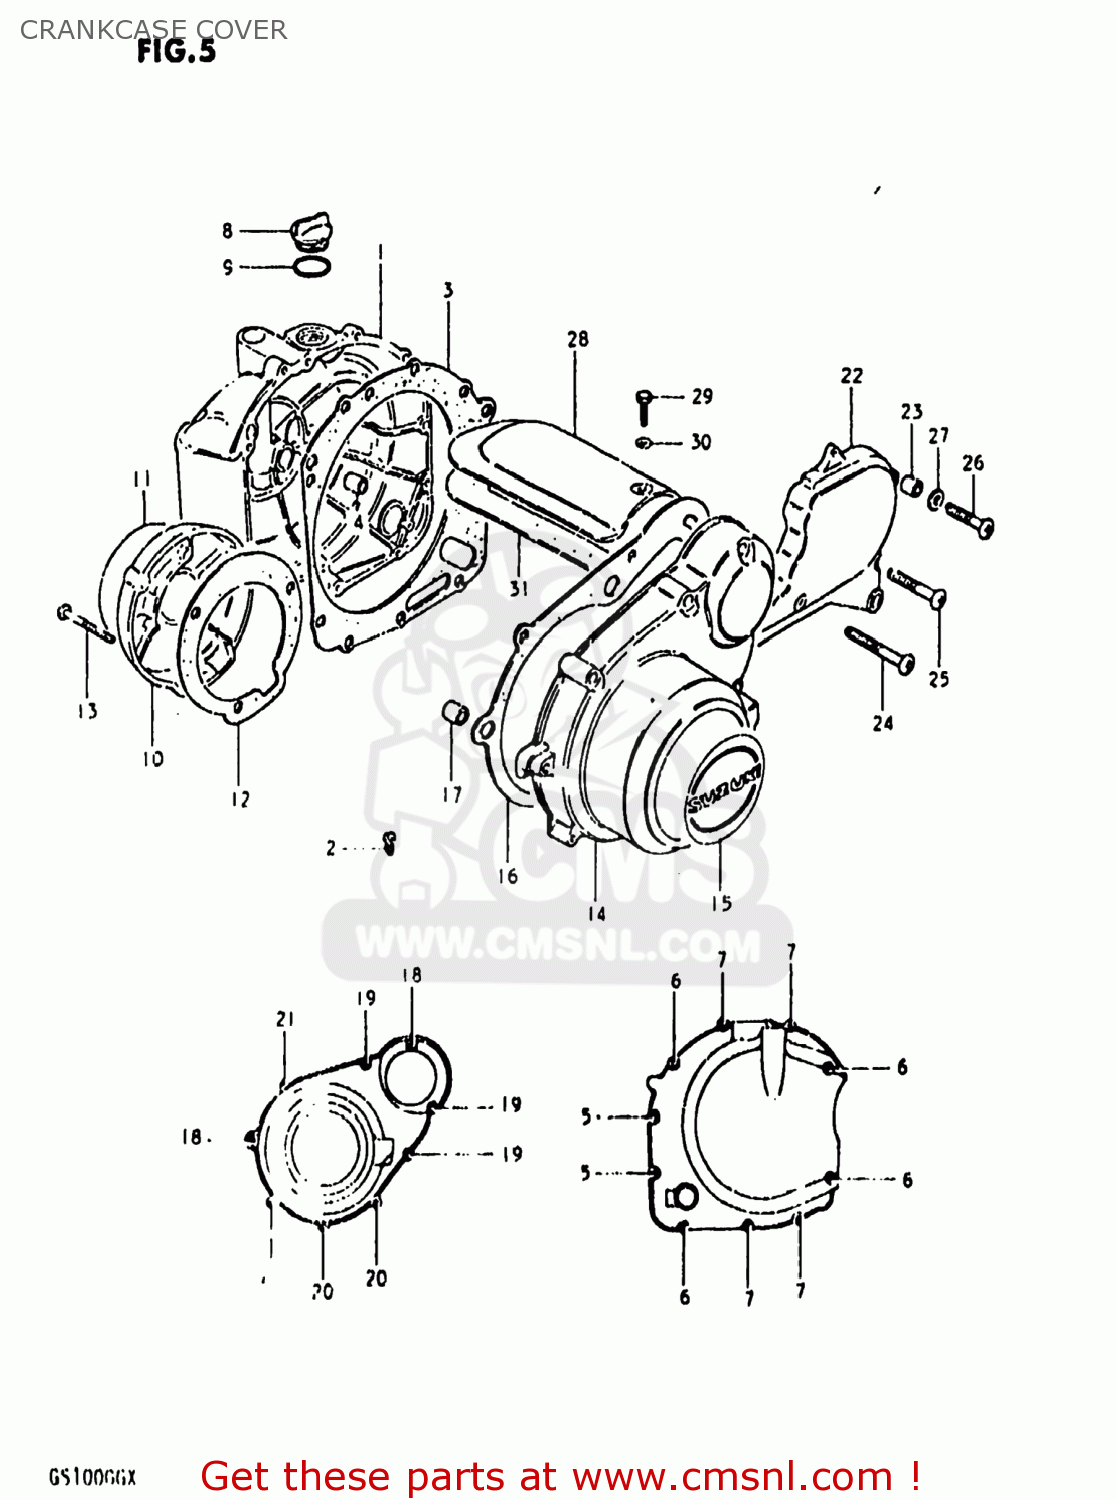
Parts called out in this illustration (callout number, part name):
1	COVER,CLUTCH
2	JET
3	GASKET,MAGNETO COVER (N (MCA)
4	PIN
5	SCREW (6X35)
6	SCREW 6X30
7	SCREW
8	CAP
9	O RING(D:2.2,ID:32)
10	COVER,CONTACT BREAKER
11	EMBLEM
12	GASKET,CONTACT BREAKER COVER (NAS)
13	SCREW
14	COVER
15	EMBLEM
16	GASKET,MAGNETO COVER (MCA)
17	PIN
18	SCREW (6X45)
19	SCREW
20	SCREW (6X35)
21	SCREW 6X30
22	COVER,SPROCKET
23	PIN
24	SCREW 6X30
25	SCREW
26	SCREW
27	WASHER
28	COVER,STARTER MOTOR
29	BOLT
30	WASHER
31	GASKET,STARTER MOTOR COVER (MCA)
